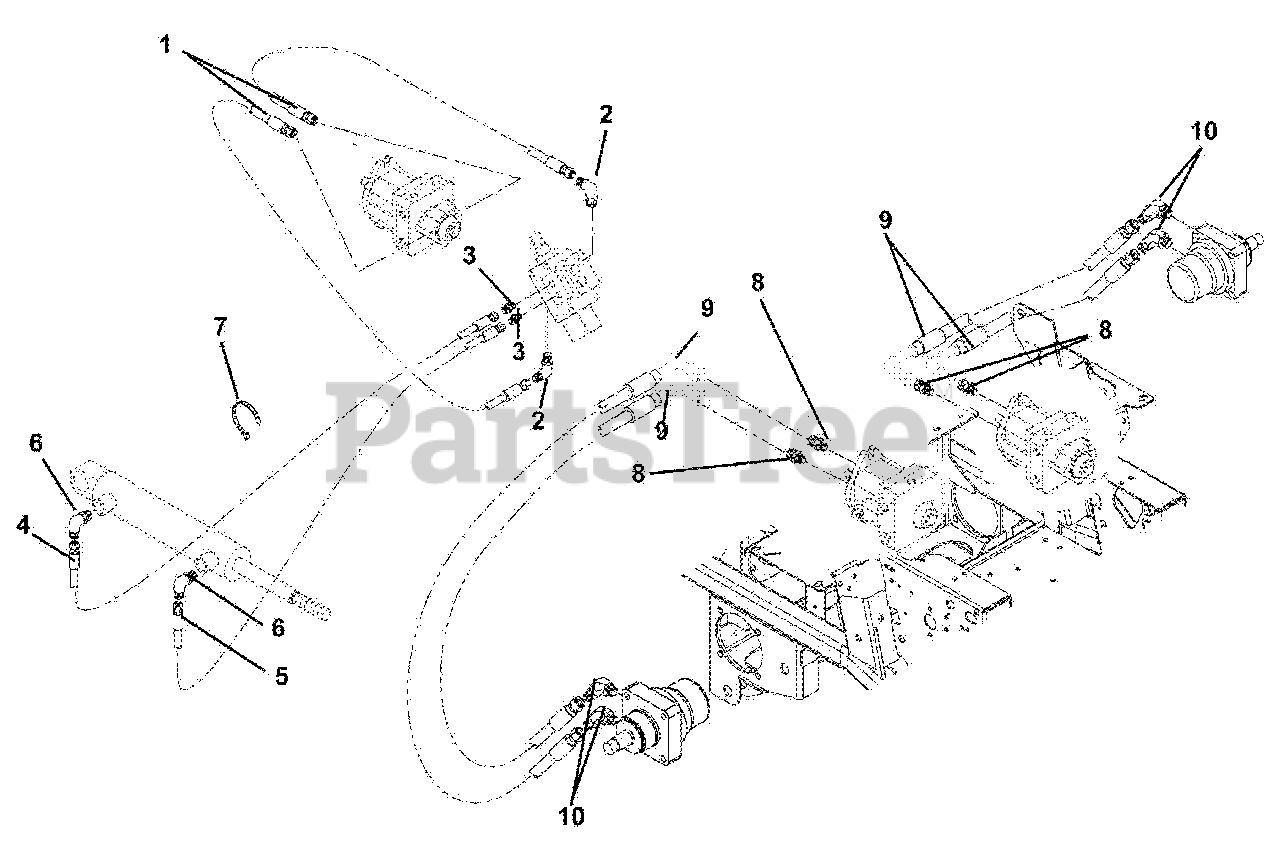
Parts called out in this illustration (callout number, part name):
1	Hose, Hydraulic
2	Hydraulic, Fitting Elbow
4	Hose, Hydraulic
5	Hose, Hydraulic
6	Fitting, Hydraulic
7	Cable Tie
8	Adapter, Face Seal 8 x 8 .50 O-Ring
9	Hose, Hydraulic .50
10	Adapter-Hydraulic Steel .875 to .75
